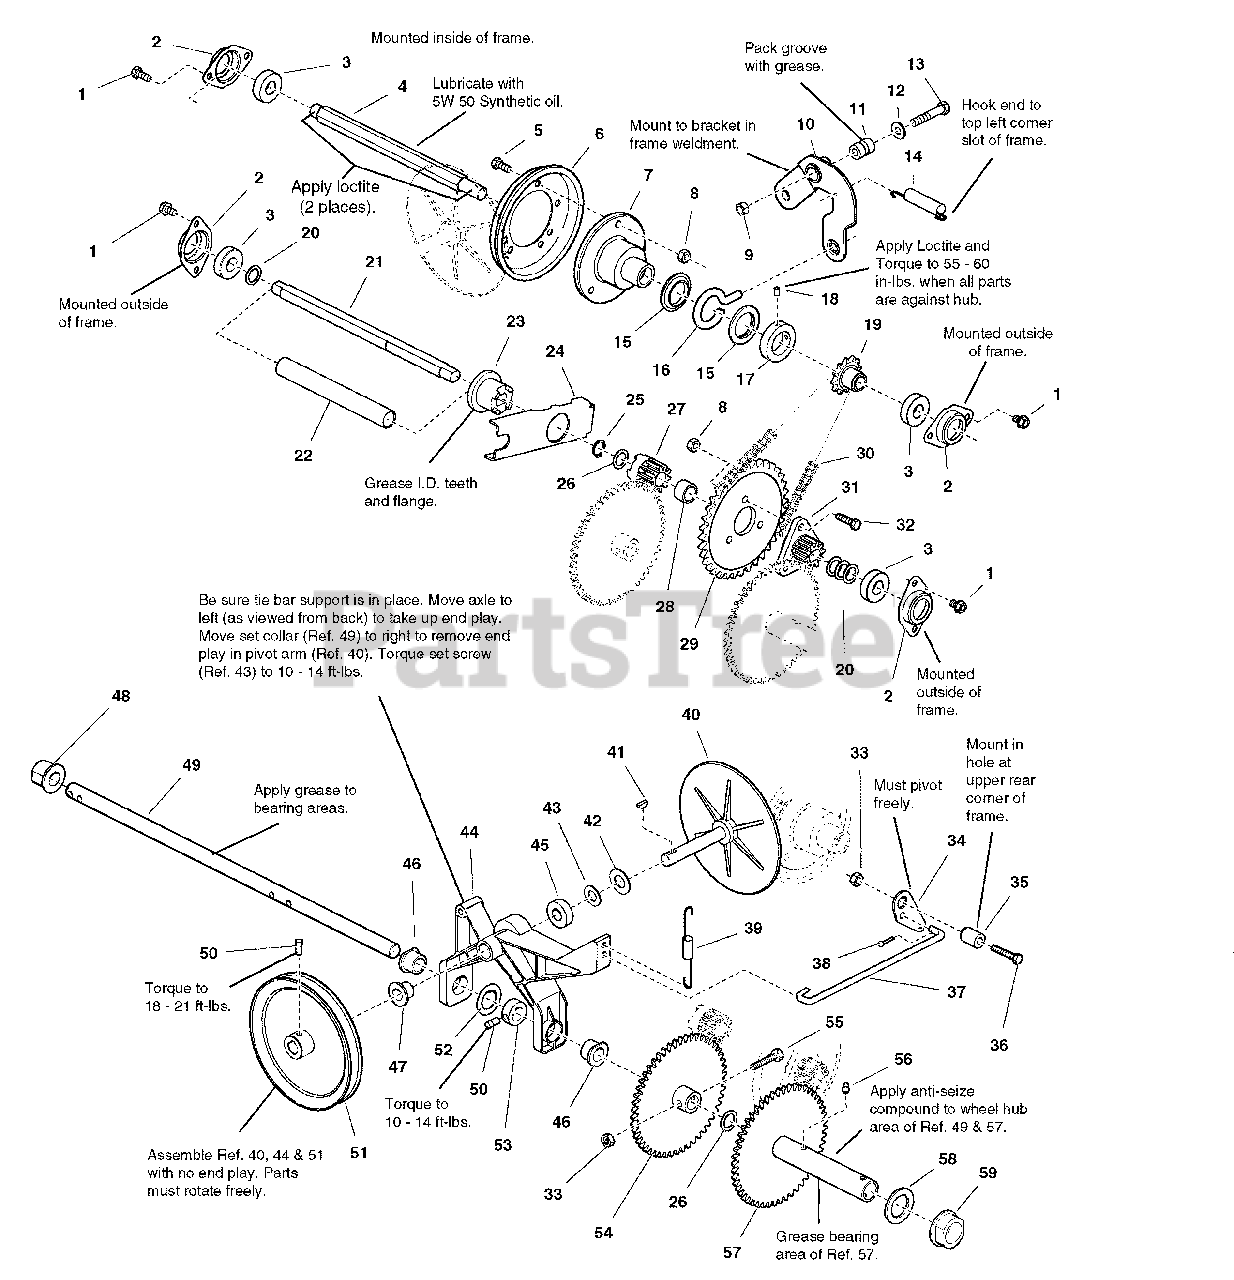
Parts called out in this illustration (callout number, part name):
1	SCREW, Hex Washer Head Taptite, 5/16-18 x 5/8
2	RETAINER, Bearing
3	BEARING, Ball
4	SHAFT, Hex
5	CAPSCREW, Hex Head, 5/16-18 x 3/4 G5
6	DISC, Friction with Insert
7	HUB, Friction Disc
8	NUT, Hex Keps, 5/16-18, Conical Washer
9	NUT, Hex Flange, 3/8-16 ESNA
10	ARM ASSEMBLY, Shift w/Bushing
11	BUSHING, 19/50 ID x 3/4 OD x 1-3/100 LG
12	WASHER, 3/8
13	CAPSCREW, Hex Head, 3/8-16 x 2 G5
14	SPRING, Extension
15	COLLAR, Thrust
16	PIN, Loop
17	COLLAR, Set
18	SCREW, Set Square Head Cup Point, 1/4-20 x 1/2
19	SPROCKET, 10 Tooth
20	WASHER, 5/8
21	JACKSHAFT, Double D
22	SPRING, Complete
23	CLUTCH, Sliding, 1/5LG, Powdered Metal
24	ARM, Clutch
25	RING, Retaining Extension
26	WASHER, 3/4
27	GEAR, Stationary Clutch
28	SPACER, Heat Treated, 31/100 LG
30	CHAIN, Roller
31	GEAR, Double D
32	CAPSCREW, Hex Head, 5/16-18 x 1
33	NUT, Hex Flange, 5/16-18 ESNA
34	BELLCRANK
35	BUSHING, 11/32 ID x 3/4 OD x 1-3/50 LG
36	SCREW, Hex Head Cap, 5/16-18 x 1 3/4
37	ROD, Pivot, 9-15/100 LG
38	PIN, Quick
39	SPRING, Extension
40	DRIVE DISC with SPINDLE
41	KEY, Woodruff, 47/250 x 5/8
42	WASHER, 3/4
43	WASHER, 5/8
44	ARM, Pivot with Bushings & Bearings
45	BEARING, Ball
46	BUSHING, 3/4 ID x 1 OD x 3/4 LG, Powder Metal
47	BUSHING, 5/8 ID x 13/16 OD x 3/4 LG, Powder Metal
48	BUSHING, 377/100 ID x 1-13/100 OD x 1 LG, Powdered Metal
49	AXLE, Round
50	SCREW, Set Square Head Cup Point, 5/16-18 x 1/2 G8
51	PULLEY AND HUB ASSEMBLY
52	WASHER, 1
53	COLLAR, Set
54	GEAR AND HUB ASSEMBLY- RH
55	CAPSCREW, Hex Head, 5/16-18 x 1-1/2 G8
56	FITTING, Lube 1/4 Drive, No Check Ball
57	GEAR AND HUB ASSEMBLY, with Bushings
58	WASHER, 1-47/250
59	BUSHING, 1-27/200 ID x 1-157/250 OD x 3/4 LG
